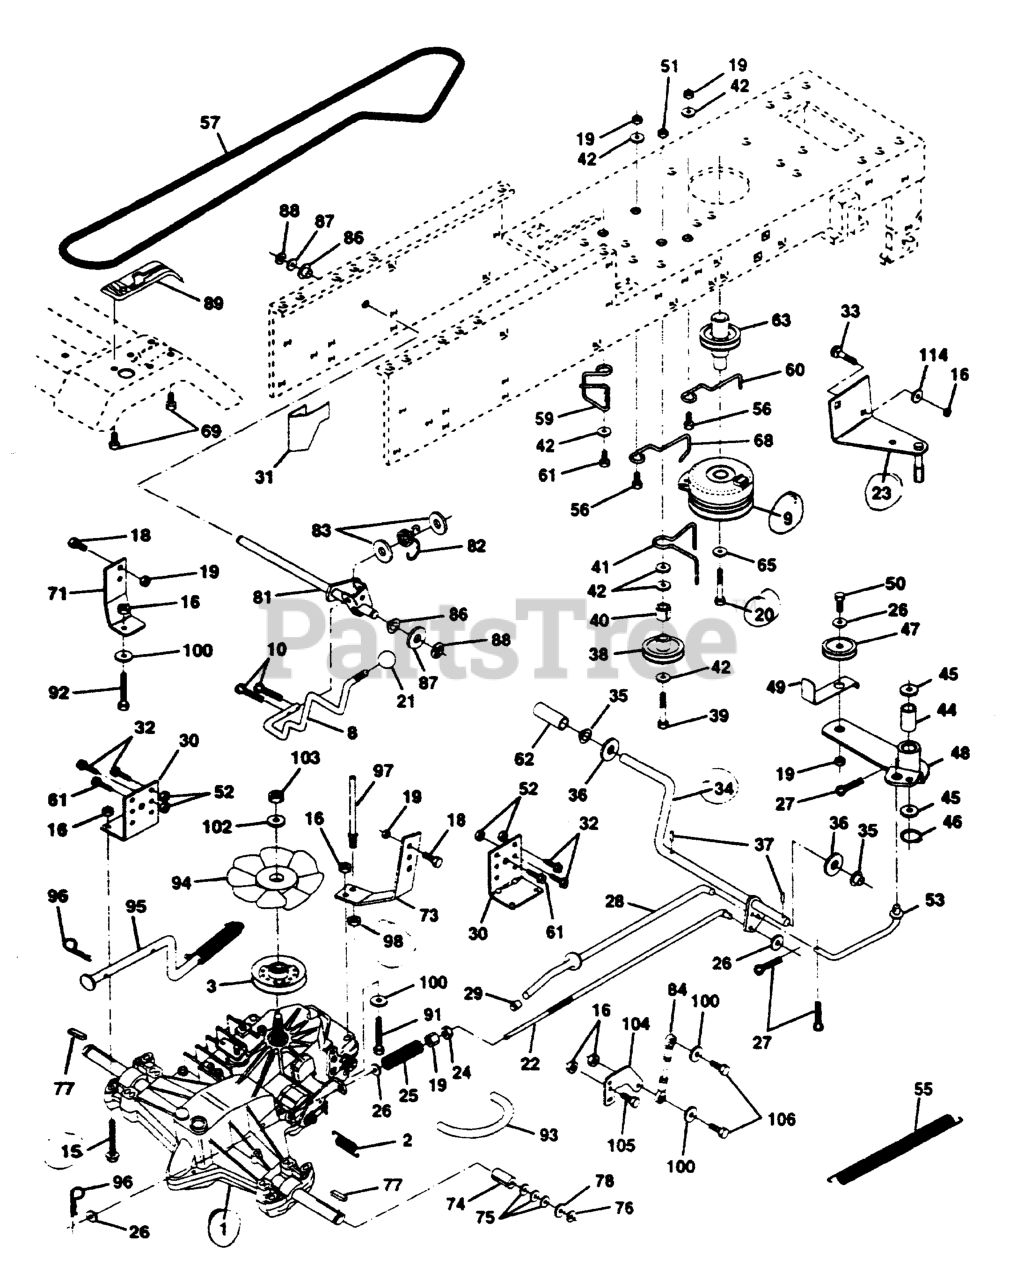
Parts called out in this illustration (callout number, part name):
1	TRANSAXLE ASSEMBLY
2	SPRING BRAKE
3	PULLEY, TRANSAXLE
9	CLUTCH.ELECT.EVX.
10	PIN COTTER
16	NUT.71038.31-18.HEX.NYLOCK
19	NUT
20	BOLT HEX
21	KNOB.DUCKHEAD.1/2
22	ROD BRAKE HYDRO
23	BRACKET, ASM CLUTCH MTG EVX
24	NUT
25	SPRING ROD LT
26	WASHER
27	COTTER PIN
28	ROD BRAKE PARK LT
30	BRACKET TRANSAXLE
31	KEEPER BELT LH
32	BOLT
33	RP BOLT 5/16-18 X3/4 ZN/YEL GR
34	SHAFT PEDAL FOOT
35	BEARING.NYLON
37	DRIVE PIN
38	PULLEY.IDLER.FLAT
41	BELT KEEPER LT NLA
42	WASHER
44	BEARING LT (2 2)
47	IDLER PULLEY
49	RETAIN BELT
50	BOLT
52	LOCKNUT
53	LINK, CLUTCH LT
55	SPRING, RETURN LT
57	DRIVE BELT, LTH & YTH TRACTORS
59	KEEPER CENTER SPAN
60	KEEPER,BLT ENG LT
61	SCREW
62	COVER, PEDAL (1 2)
63	PULLEY, CLUTCH ELECT EVX
65	LOCKWASHER
69	SCREW.HI-LO.CONSOLE
71	STRAP LH TORQUE
73	STRAP RH TORQUE
74	SPACER SPLIT
77	SQUARE KEY
81	SHAFT ASSY
82	SPRING,TORSION
83	WASHER
84	ROD.TIE.BALL.4.75
86	BUSHING.STEERING.ROD LTB-WSL
89	CONSOLE HYDRO LT
91	BOLT.FIN HEX 5/16-18UNC X2 1/4
92	HEX BOLT
93	LINE FUEL HYD 4"
94	FAN 7" HYDRO
95	CONTROL ARM, BYPASS HYDRO
96	RETAINER M
97	KEEPER BELT RH
100	WASHER M
103	NUT.HEX.1/2-20
104	CONTROL ARM
106	BOLT.5/16-18X1-1/4 FULL.THREAD
114	WASHER - 15X7.3X1.6
